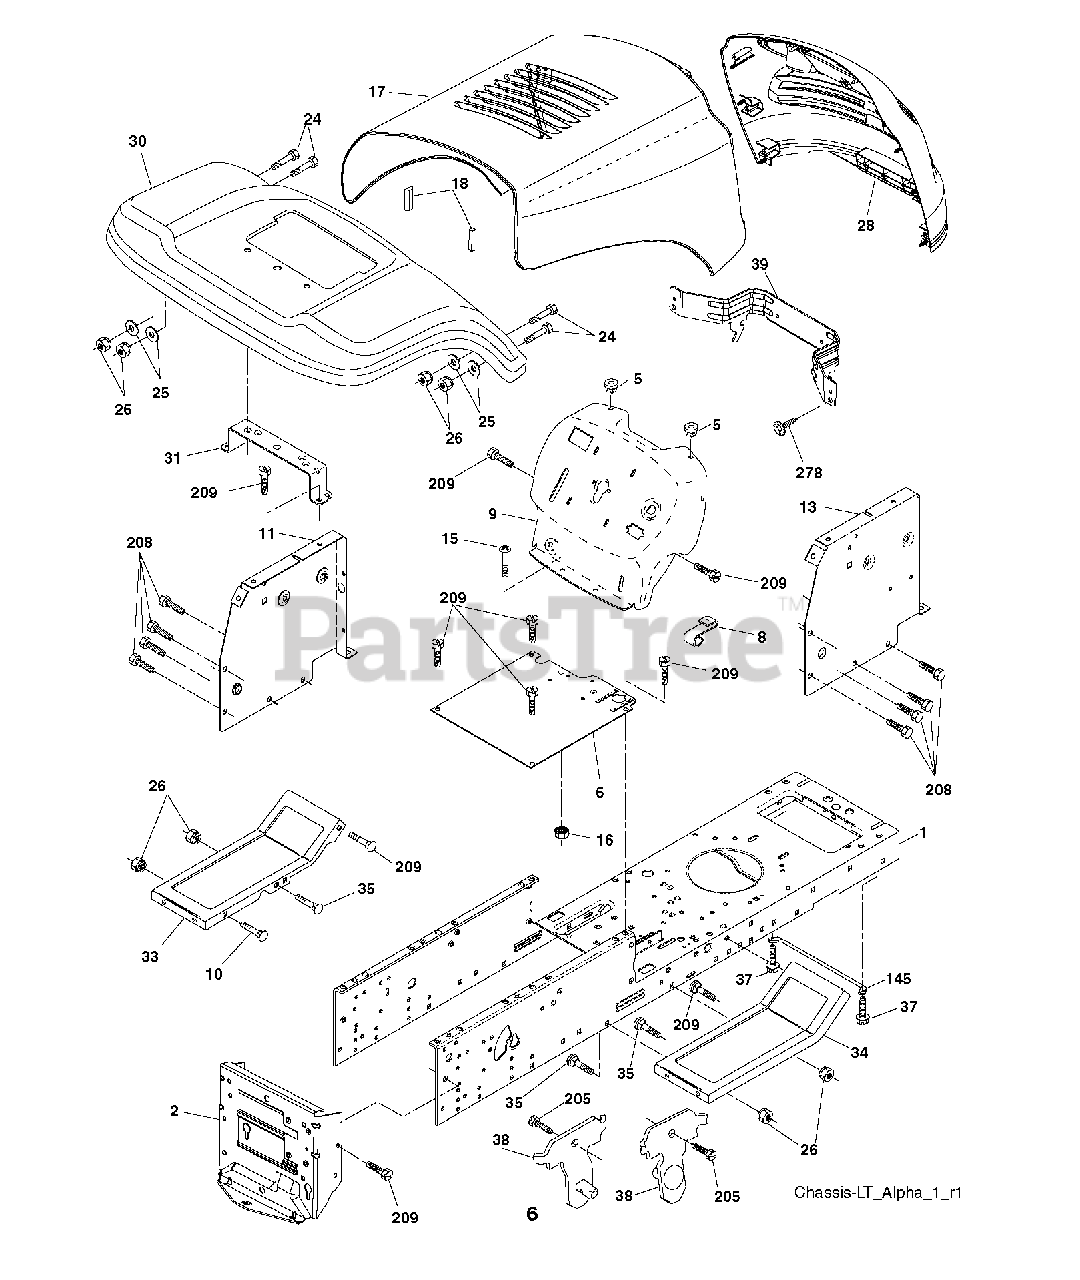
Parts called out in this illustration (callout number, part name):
1	CHASSIS
2	DRAWBAR, 12GA
5	BUMPER.RUBBER.HOOD
8	CLIP RETAINER
9	FENDER LT SH
10	BOLT D
11	PANEL.DASH.LH.LTX
13	PANEL DASH RH
16	NUT
17	GRILLE.ALPHA.LT.NO LIGHTS
18	BUMPER.HOOD.LARGE.1.75"
25	WASHER
26	NUT
28	GRILLE.ALPHA.LT.NO LI
30	CONSOLE.SVC.SHIFT.LTST.5SP
31	BRACKET FENDER
33	FOOTREST.PNT.RH
38	BRACKET.ASM.PIVOT.MOWER.REAR
39	BRACKET.PIVOT.ALPHA.LT
145	ROD.PIVOT.HOOD
208	SCREW 3/8-16X1/2
209	SCREW, 3/8-16X3/4
278	SCREW.#10 X 0.750.BOS THREAD
